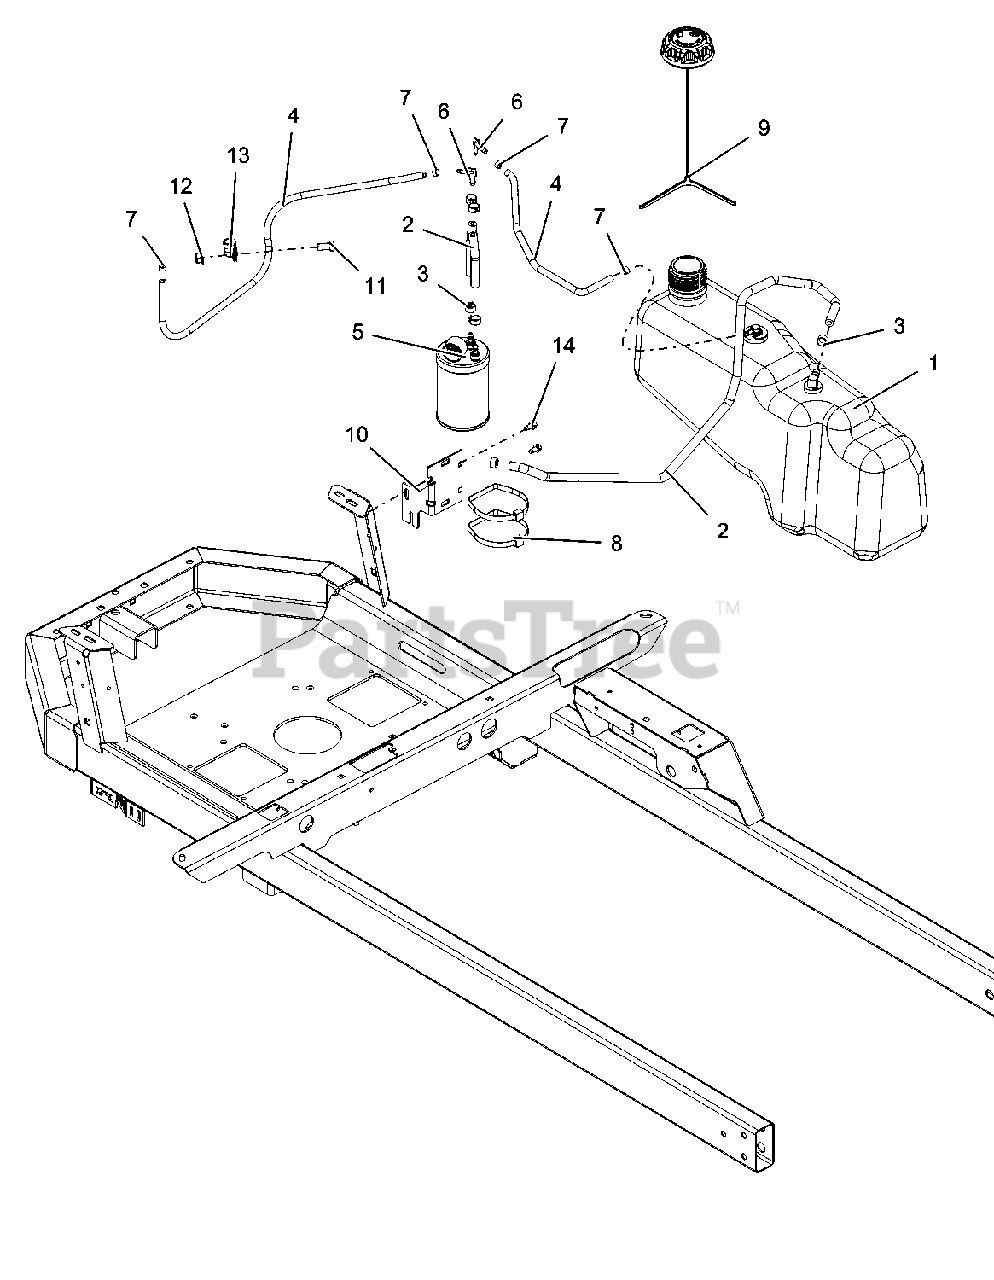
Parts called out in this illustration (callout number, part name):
1	ASM, TANK NON-PERM FUEL
2	HOSE, .25 LOW-PERM BULK GAS-
3	CLAMP, FUEL LINE
4	HOSE, .188 LOW
5	CARBON CANISTER, 300CC
6	FITTING-3/16X1/4 90DEGREE VAC
7	CLAMP - HOSE, SPRING .188
8	P-PLASTIC TIE STRAP LARGE
9	CAP, FUEL VENT-IN 2.25" RATCHET
10	BRKT, MOUNT -CARB CANISTER-BLACK
11	BLT-HEX .38-16X.75 GR5 YWZC
12	NUT-LK-NYL-FLG .38-16 YWZC
13	CLAMP, CUSHIONED STEEL
14	SCR-TAP .25-20X.50 HWH TR YWZ
